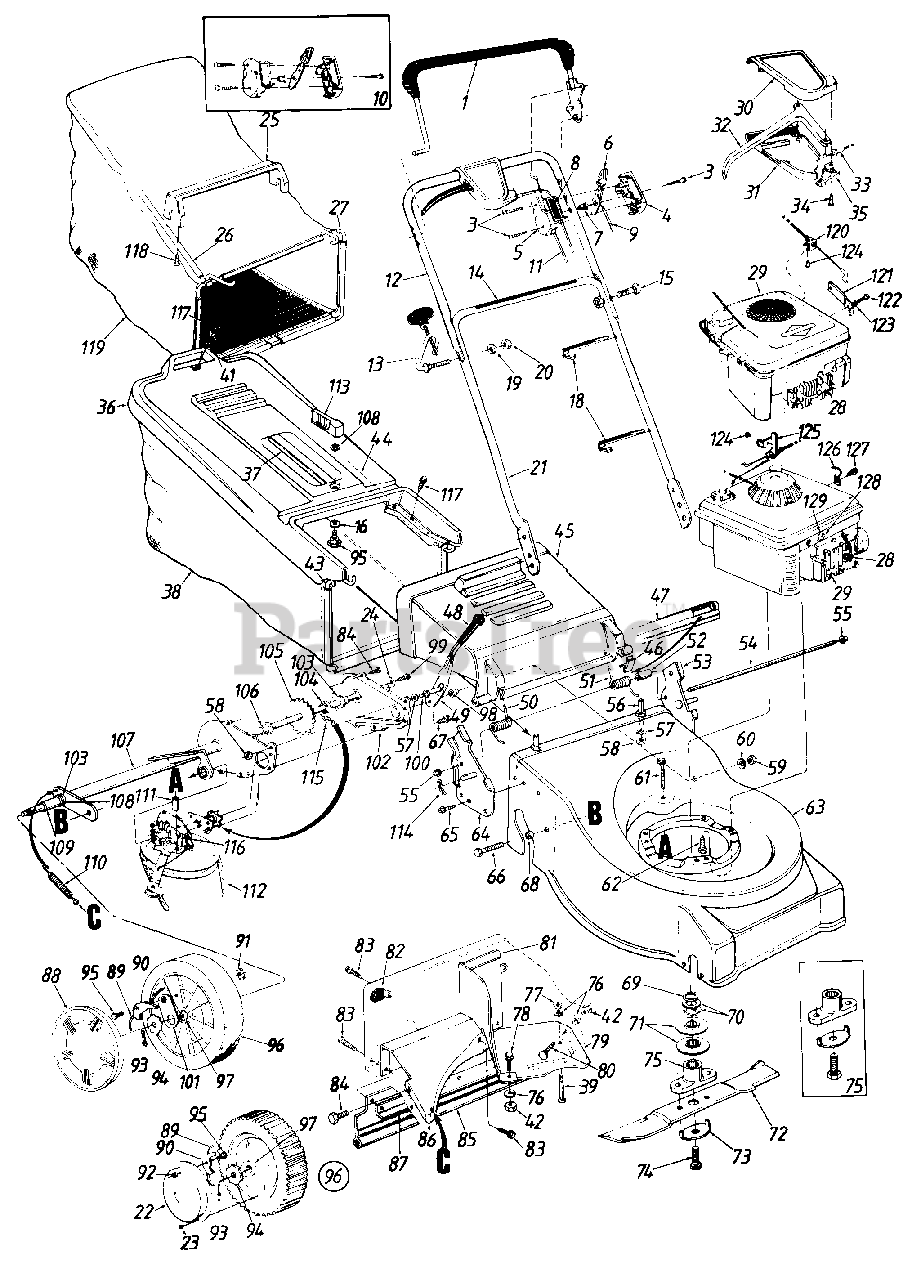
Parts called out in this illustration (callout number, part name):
1	Control Handle Ass'y.
3	Truss Mach. B-Tap Scr. #12 x 1.5" Lg.
4	Control Panel Half
5	Clutch Panel Half
6	Throttle Control Lever
7	Control Disc Pin
8	Control Label-Throttle
9	Throttle Wire-53" Lg.
10	Control Housing Comp.
11	Control Cable-46" Lg.
12	Upper Handle (Painted)
13	Rope Guide Bolt
14	Instruction Label-Handle
15	Curved Carriage Bolt 5/16-18 x 1.38" Lg.
16	Bowed Washer
18	Cable Tie
19	L-Wash. 5/16" I.D.
20	Hex Nut 5/16-18 Thd.*
21	Lower Handle (Painted)
22	Hub Cap
23	Pan HD. Tap Scr. #12 x .50" Lg.
24	Bell-Wash. .265" I.D. x .75"
25	Bag Handle
27	Front Catcher Frame
28	Spark Plug Boot
29	Engine
30	Control Cover Half-Upper
31	Control Cover Half-Lower
32	Control Lever
33	Drive Cable-53" Lg.
34	Flat C-Sunk Hd. Tap Scr. #10 x .75" Lg.
35	Cable Mtg. Cap
36	Hardtop Bag Cover
37	Hardtop Handle
38	Grass Bag
39	Truss Mach. Scr. 1/4-20 x 1.0" Lg.
41	Fl-Wash. .281" I.D. x .62
42	Hex Nut 1/4-20 Thd.
43	Front Catcher Frame
44	Rear Catcher Frame
45	Chute Deflector
46	Deflector Plug
47	Seal-Extrusion
49	Spring Lever
50	Torsion Spring-R.H.
51	Torsion Spring-L.H.
52	Spacer.255" I.D.
53	Handle Brkt. Ass'y.-L.H.
54	Hinge Pin 17.75" Lg.
55	Cap Speed Nut
56	Shld. Pin 3/8-24 x 1.43" Lg.
57	L-Wash. 3/8" I.D.
58	Hex Jam Nut 3/8-24 Thd.
59	Hex L-Nut 3/8-24 Thd.
60	Bell-Wash. .38" I.D. x .88"
61	Hex Wash. Hd. Tap Scr. 1/4-20 x 1.5" Lg.
62	Hex L-Wash. Hd. Scr. 3/8-16x 1" Lg.
63	21" Deck Ass'y.
64	Handle Brkt. Ass'y.-R.H.
65	Hex L-Wash. Hd. AB-Tap Scr. 1/4 x.62" Lg.
66	Hex Wash. Hd. Tap Scr. 3/8-16 x .75" Lg.
67	Hex Wash. Hd. Tap Scr. 1/4 -20 x .5" Lg.
68	Spacer.383" I.D.
69	Serrated Washer 1.0" I.D.
70	Wave Washer 1.005" I.D.
71	Serrated Pulley Half
72	21" Blade
73	Blade Bell-Wash. .44" I.D.
74	Hex Bolt 7/16-20 x 1.5" Lg. (Grade 5)
75	Blade Adapter Kit
76	L-Wash. 1/4" I.D.
77	Hex Jam Nut 1/4-20 Thd.
78	Hex Bolt 1/4-20 x .85" Lg.
79	Rear Belt Baffle
80	Carr. Bolt 1/4-20 x .50" Lg.
83	Torx Mach. AB-Tap Scr. 1/4 x .62" Lg.
84	Hex B-Tap Scr. 1/4 x .38" Lg.
85	Rear Flap
89	Plastic Spring
90	Pawl.345" I.D.
91	Weld Nut 1/4-20 Thd.
92	Hex Ins. L-Nut 1/4-20 Thd.
93	Cotter Pin 1/8" Dia.
94	Ratchet Wheel 1.62" O.D.
95	Shld. Bolt .342" Dia. x .268"
96	Wheel Ass'y. Comp.-Rear
97	Bearing 1/2" I.D.
98	Shld. Spacer .50" Dia.
99	Hex Bolt 1/4-20 x .62" Lg. (Grade 5)
100	Shld. Pin 3/8-24 x 1.43" Lg.
101	Pawl Plate
104	Fl-Wash. .531" I.D. x .93"
105	Rear Axle Ass'y.
106	Hex Flange Bearing
109	Spacer. 513" I.D.
110	Extension Spring 3.8" Lg.
111	Spacer.325" I.D.
112	V-Belt
113	Grass Catcher Locking Knob
114	Internal Cotter Pin 5/16" Dia.
115	#48 Chain .50" Pitch x 30 Links
116	Transmission Comp.
117	Hex L-Wash. H.D. AB-Tap Scr. 1/4 x .62" Lg.
118	Hex AB-Tap Scr. #12 x 1.25" Lg.
119	Grass Bag
120	Cable Mtg. Brkt.
121	Mounting Brkt.
122	Truss Mach. Scr. #10 x .5" Lg.
123	L-Wash. #10 I.D.
124	Pop Rivet .156" Dia.
125	Cable Brkt.
126	Cable Clamp
127	Hex B-Tap Scr. #10 x .38'1 Lg.
128	Hex Tap Scr. #10 x .62" Lg.
129	Cable Clamp
